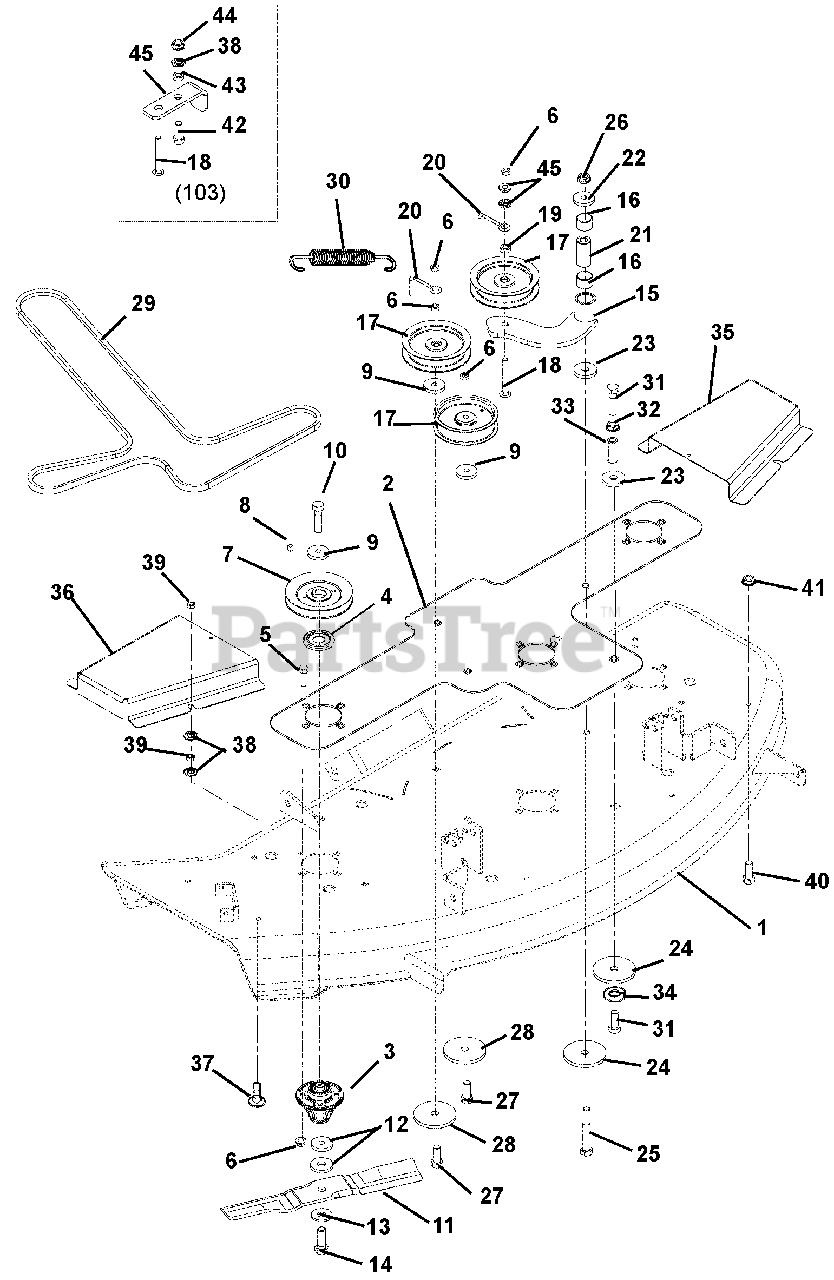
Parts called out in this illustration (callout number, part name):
1	WELDMENT, 50" DECK
1	WMT, 40" STAMPED DECK (ARIENS)
2	50" DOUBLER PLATE
2	DOUBLER PLATE, 40" DECK
3	SPINDLE ASSEMBLY
4	DUST CAP
5	@BLT-RDHDSQNK .38-16X1.25 G5YZ
6	@NUT-LK-NYL-FLG .38-16 YWZC
7	SHEAVE, 4.75 DIA A-SECTION
7	SHEAVE, 4.25 DIA A-SECTION
8	KEY, SQ .25 X .38 X .25
9	WSHR,FLT STL.406X1.50X.245YWZC
10	BLT-HEX .38-16X1.0 GR8 YZ EP30
11	BLADE
11	MOWER BLADE, 13.94"
12	WSHR-FLT .640X1.75X.250 YWZC
13	WSHR-BLVL .669X1.535X.138
14	BLT-HEX .62-18X1.75 GR8 YWZC
15	WMT, IDLER ARM
16	BRG, 1.00 X 1.12 X .75
17	IDLER, FLAT .38X4.00X1.06
18	@BLT-RDHDSQNK .38-16X3.50 G5YZ
18	@BLT-RDHDSQNK .38-16X2.50 G5YZ
19	BSHG-SLV .391X.688X.52 PM
20	BELT FINGER
21	BSHG, SPCR .502X.997X2.03 PM
22	WSHR-FL-STL.511X1.441X.125 YWZ
23	WSHR-FL-STL .515X1.625X.250 YZ
24	WASHER, FLAT .531X3.000X.25
25	@BLT-HEX .50-13X3.50 GR5 YWZC
26	@NUT-LK-TOP-FLG .50-13 YWZC
27	@BLT-HEX .38-16X2.75 GR5 YWZC
28	WSHR-FL-STL .469X2.00X.25 YWZC
29	V-BELT, A-WRAPPED
29	V-BELT, HA-WRAPPED
30	EXTENSION SPRING
31	@BLT-HEX .50-13X1.25 GR5 YWZC
32	NUT-SPNLK-FLG .50-13 YWZC
33	NUT, COUPLING 1/2-13X1.75 YWZC
34	@WSHR-LK .50X.125 REG YWZC
35	BELT COVER, LEFT
35	BELT COVER. LEFT 40"
36	BELT COVER, RIGHT
36	BELT COVER, RIGHT 40"
37	@BLT-RHDSHSQNK.31-18X1.25 G5YZ
38	@WSHR-FL-STL.38X.875X.083 YWZC
39	@NUT-LK-NYL-FLG .31-18 YWZC
40	@BLT-HEX .31-18X.75 GR5 YWZC
41	@NUT-SPNLK-FLG .312-18 YWZC
42	@BLT-HEX .38-16X1.00 GR5 YWZC
43	BSHG-SLV .377X.624X.235
44	@NUT-LK-TOP-FLG .38-16 YWZC
45	BELT FINGER
45	BSHG-FLG .406X.88X.270X.140
